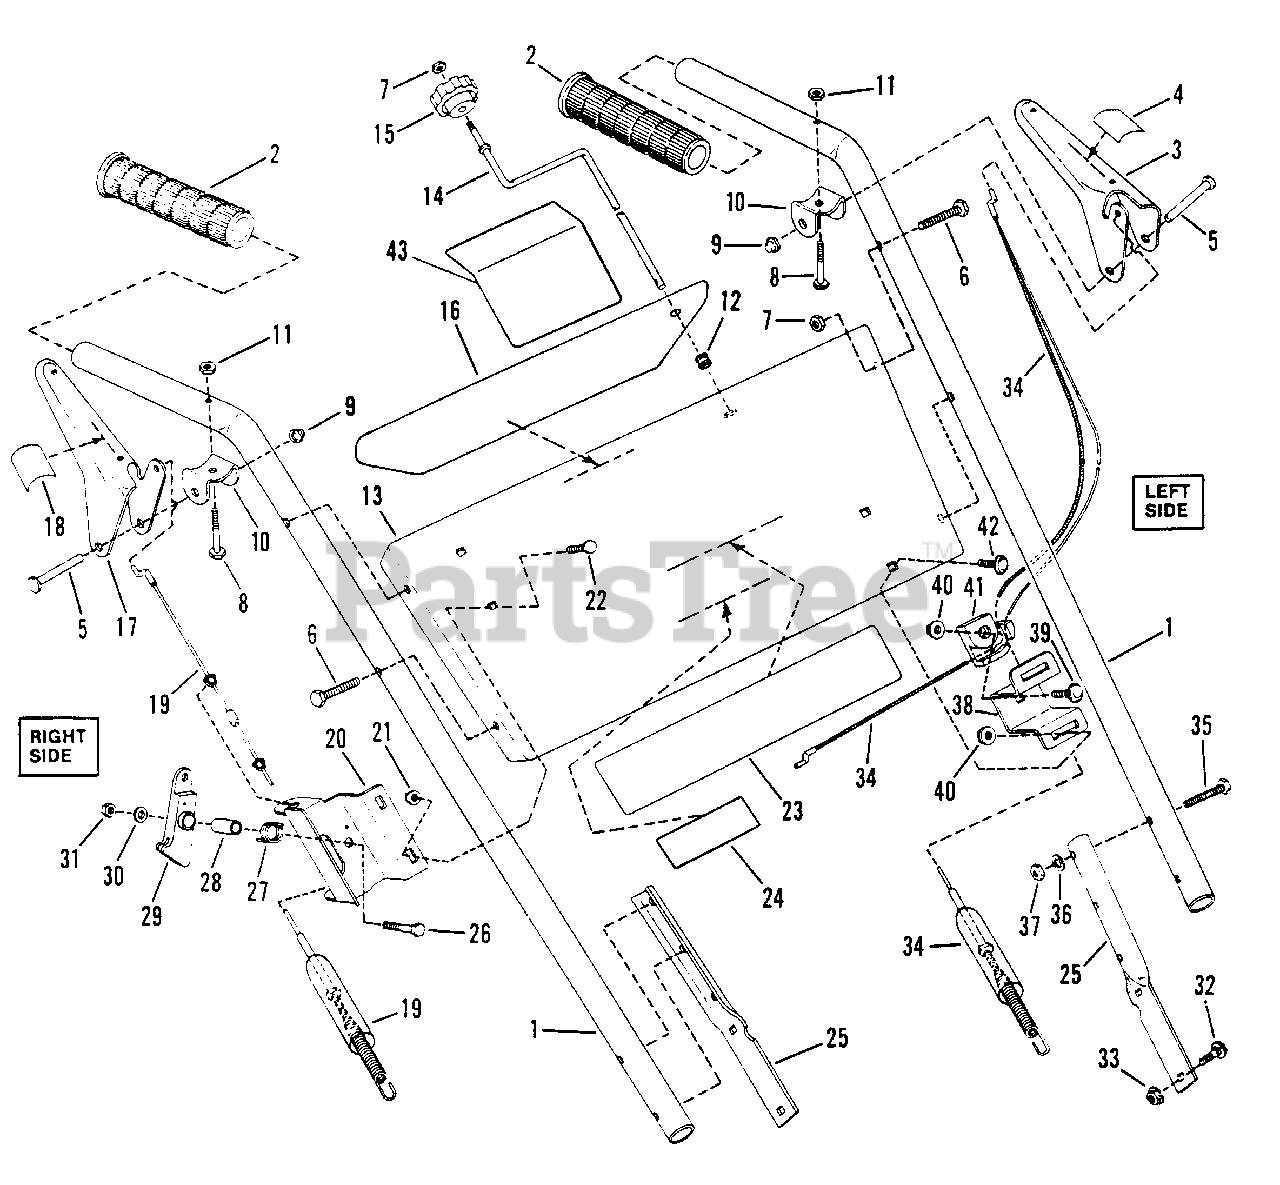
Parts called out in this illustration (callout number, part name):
1	HANDLE BAR (SERIES 1)
2	GRIP, Handle
3	HANDLE, Left Side (SERIES 1)
4	DECAL, Traction Clutch (SERIES 1)
5	PIN, 1/4x1-7/8" Clevis
6	SCREW, 5/16-18x1-1/2" Hex Head Cap
7	NUT, 5/16-18 Hex Center Lock
8	SCREW, 1/4-28x1-3/8" Hex Head Cap
9	NUT, 1/4" Push
10	BRACKET, Handle
11	NUT, 1/4-28 Hex Top Lock
12	BUSHING
13	PANEL, Control
14	CRANK, Chute
15	KNOB, Chute Crank
16	DECAL, Instruction
17	HANDLE, Right Side
18	DECAL, Blower Clutch (SERIES 1)
19	CABLE, Auger Right Side (SERIES 1 & 2) (Replaces 1-8982)
20	BRACKET
21	NUT, #10-24 Hex Flange Lock
22	BOLT, #10-24x1/2" Flat Head Carriage
23	DECAL, SNAPPER
24	DECAL, Model I422
25	BRACE, Handle Bar
26	SCREW, 1/4-20x1" Hex Head Cap
28	SPACER
29	CAM LOCK
30	WASHER, 1/4 Flat
31	NUT, 1/4-20 Hex Center Lock
32	BOLT, 5/16-18x5/8" Carriage
33	NUT, 5/16-18 Hex Flange Lock
34	CABLE, Clutch, Left Side (SERIES 1 & 2) (Replaces 1-8981)
35	SCREW, 5/16-18x1-112" Hex Head Cap
36	WASHER, 5/16 internal Tooth Lock
37	NUT, 5/16-18 Hex
38	BRACKET, Cable Guide Support
39	BOLT, 1/4-20x3/4" Carriage
40	NUT, 1/4-20 Hex Flange Lock
41	GUIDE, Cable
42	BOLT, 1/4-20x1/2" Carriage
43	DECAL, Control 524 (Black & Red & Silver)
